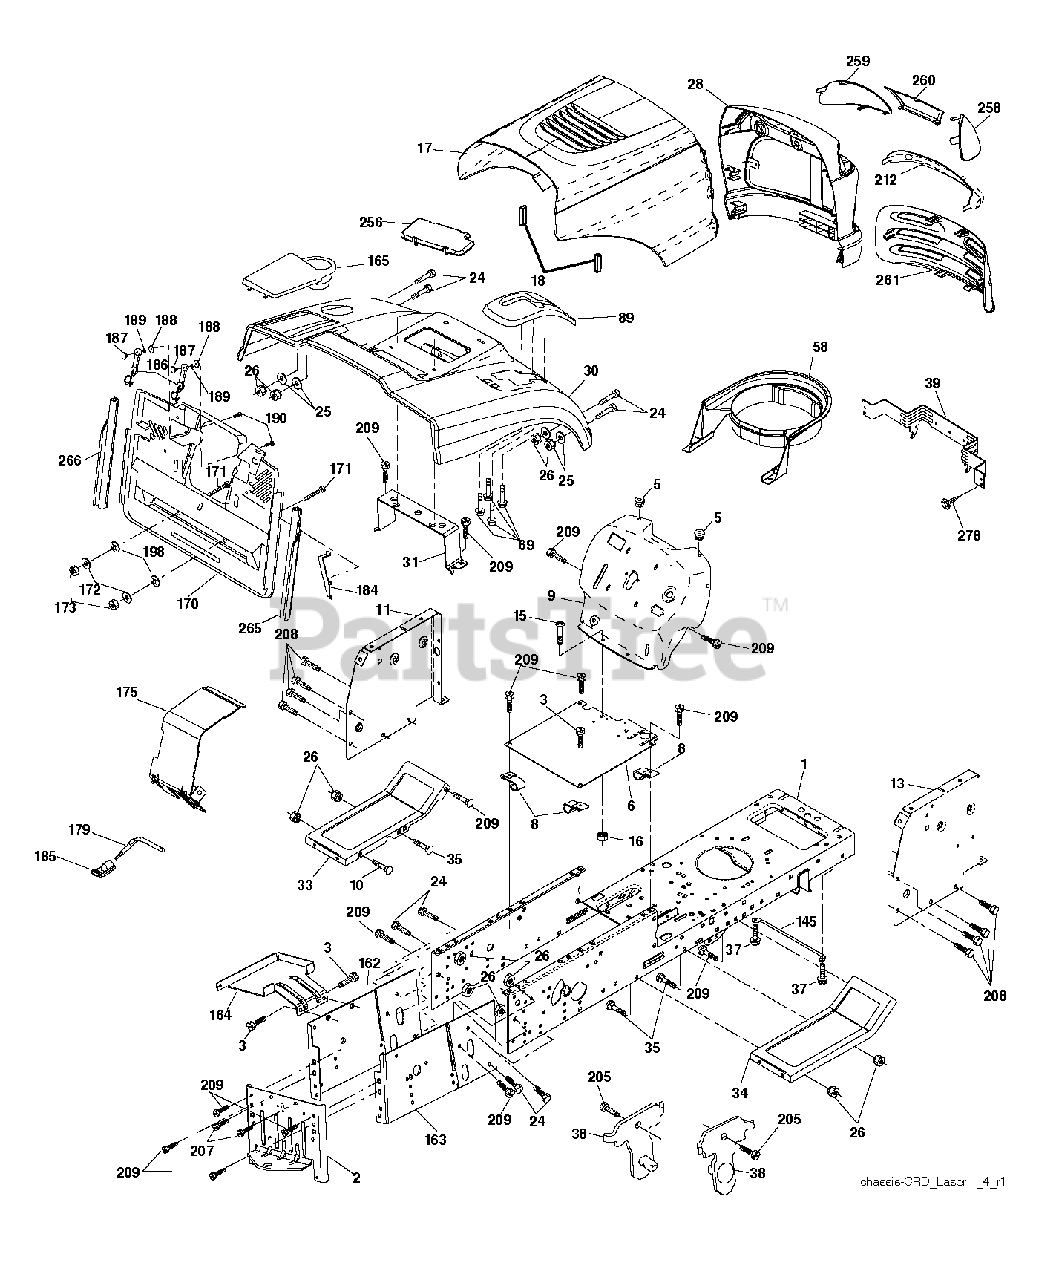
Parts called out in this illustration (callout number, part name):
1	CHASSIS
3	SCREW 3/8-16X3/4
5	BUMPER.RUBBER.HOOD
8	CLIP,INSULATOR
9	FENDER LT SH
10	BOLT D
11	PANEL.DASH.LH.LTX
16	NUT
18	BUMPER.HOOD.LARGE.1.75"
25	WASHER
26	NUT
28	GRILLE.LASER II.DUAL.
30	FENDER.PNT.CRD.MS428 K
31	BRACKET SUPPORT FENDER
39	BRACKET PIVOT
58	DUCT.INTAKE.AIR.KAW
69	SCREW.HI-LO.CONSOLE
145	ROD.PIVOT.HOOD
164	SUPPORT
165	FENDER.PNT.CRD.
171	BOLT
172	WASHER
184	BRACKET.ACTUATOR.BAGGER.SRD
187	WELDNUT
207	SCREW, 5/16-18 X 1/2
208	SCREW 3/8-16X1/2
209	SCREW, 3/8-16X3/4
256	FENDER.PNT.CRD
258	LENS.LASER.2PC.LH.CLEAR.SVC
259	COVER.LENS.LASER.II
278	SCREW.#10 X 0.750.BOS THREAD
